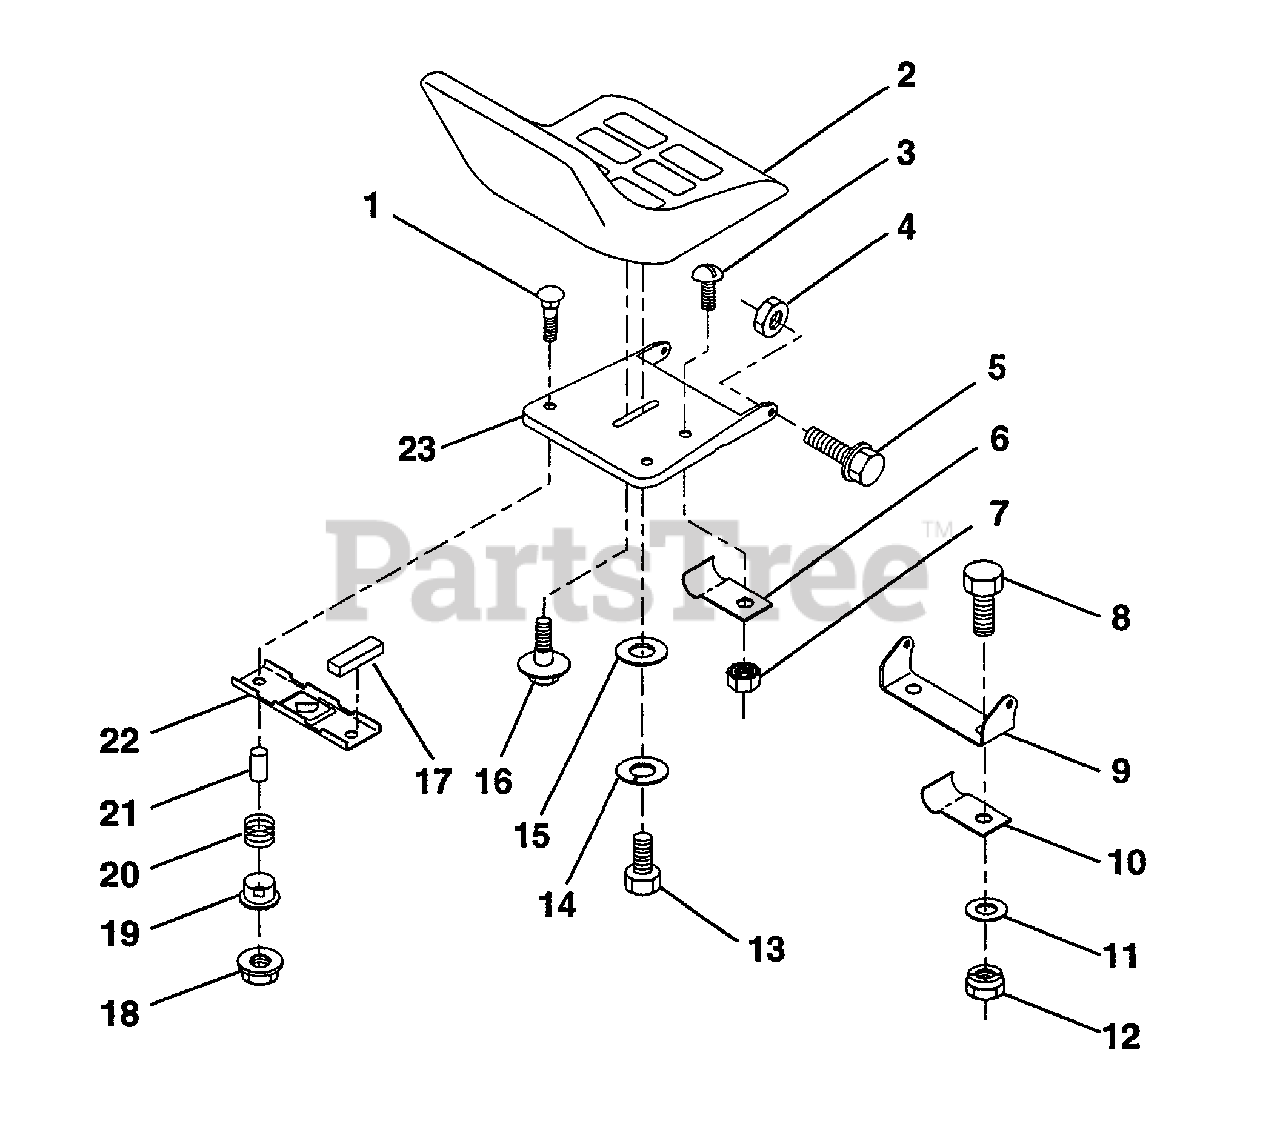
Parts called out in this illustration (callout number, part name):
1	Bolt, Carriage 1/4-20 x 1-1/4
2	Seat
3	Screw, Slotted Pan Head #10-32 x 1/2
4	Nut, Crownlock 5/16-18
5	Bolt, Shoulder 5/16-18 UNC
6	Clip, Insulated
7	Nut, Keps #10-32 UN F
8	Bolt, Fin Hex 3/8-16 UNC x 3/4
9	Bracket, Pivot Seat
10	Clip, Insulated
11	Washer 12/32 x 3/4 x 10 Ga.
12	Nut, Crownlock 3/8-16 UNC
13	Bolt, Fin Hex 1/2-13 UNC x 7/8 Gr. 5
14	Washer,Lock Hvy Helical Spring
15	Washer, 17/32 x 1-3/16 x 12 Ga.
16	Bolt, Shoulder
17	Strip, Foam
18	Nut, Hex Large Flange Lock
19	Bushing, Snap
20	Spring, Compression
21	Spacer, Split 28 Id. x .88 Lg.
22	Bracket, Switch, Mounting
